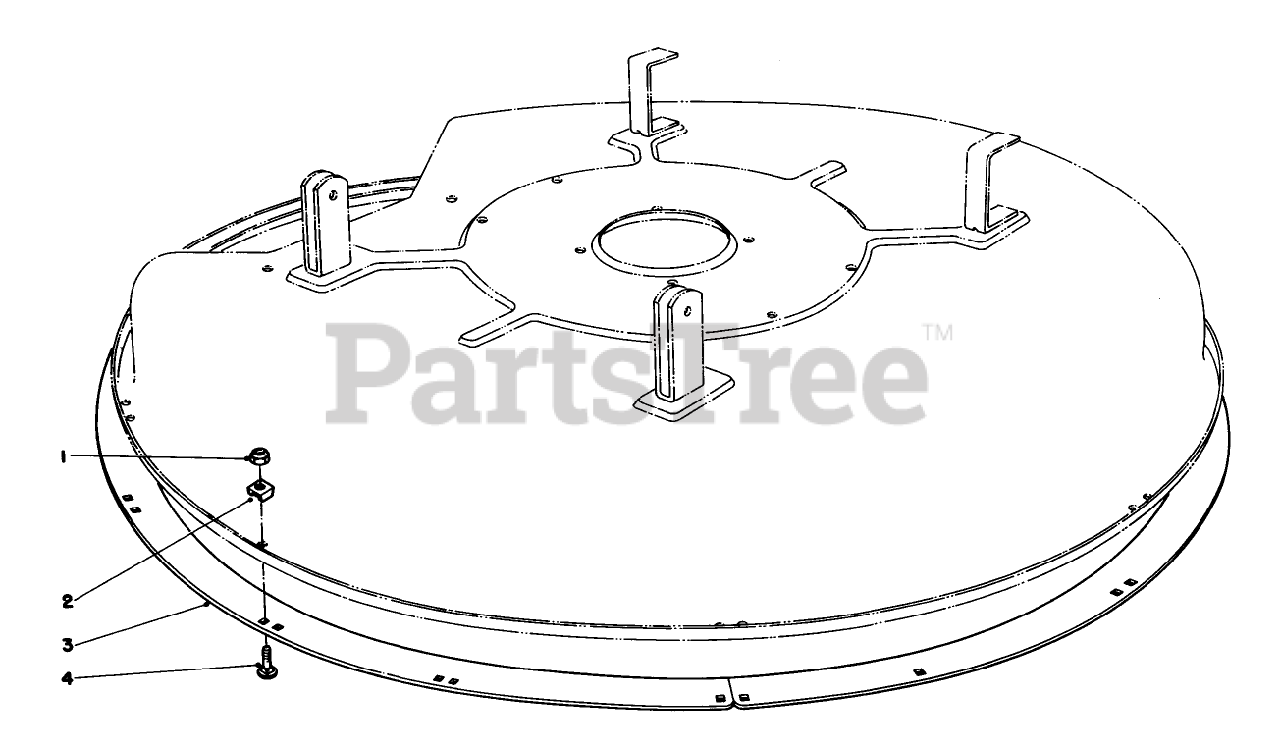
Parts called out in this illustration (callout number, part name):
1	NUT-LOCK, NI
3	DECK RING *B
4	BOLT-CARR
